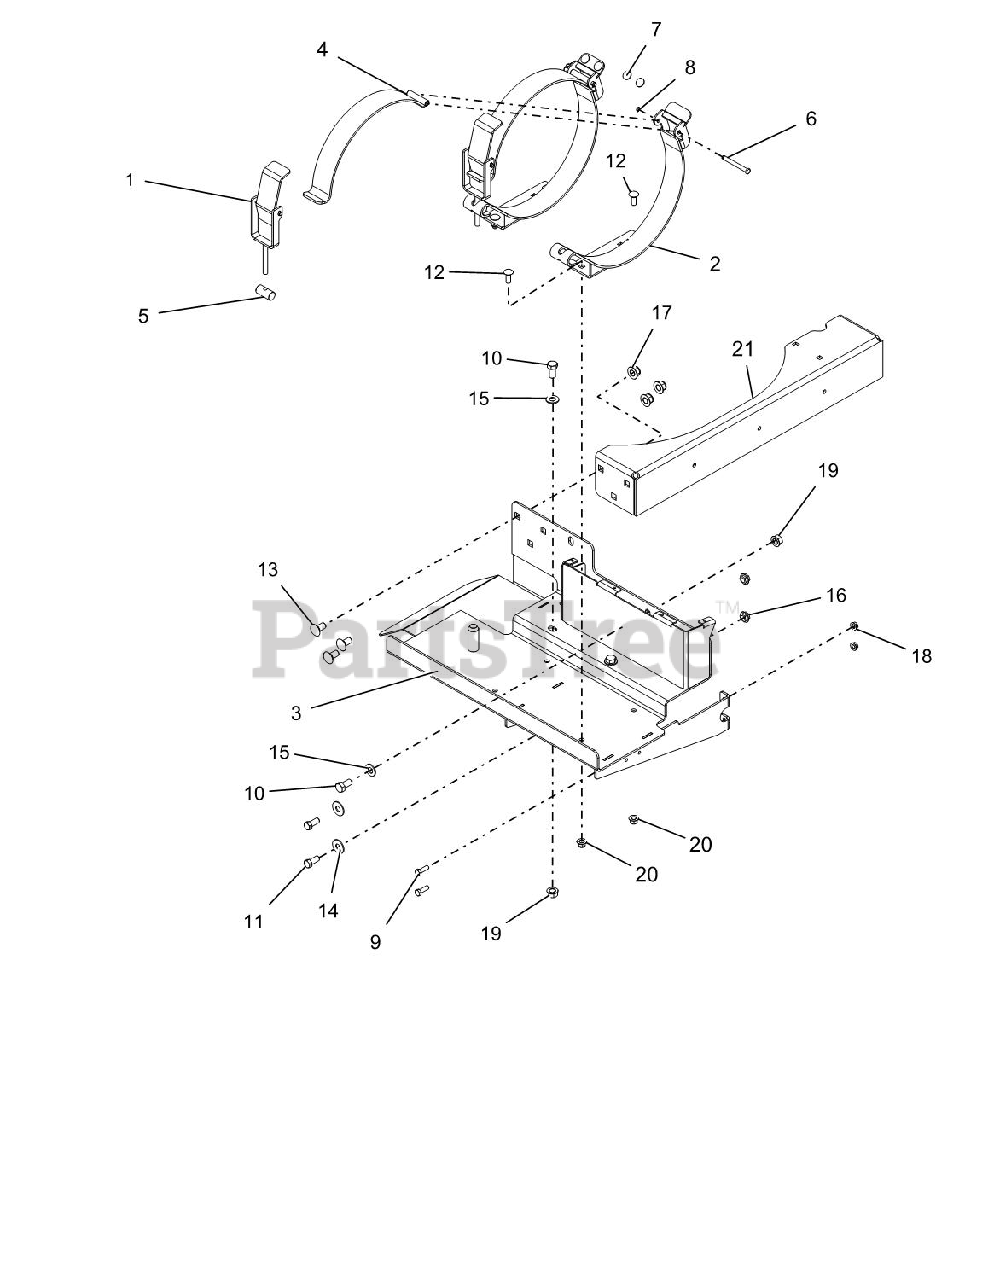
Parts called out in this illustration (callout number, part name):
1	ASM,TOGGLE CLAMP
2	WLDMT, CLAMP LP TANK
3	RH LP TANK MTG W/SAFETY DECAL
4	LP TANK CLAMP W/SAFETY DECAL
5	PIVOT, LP CLAMP HANDLE
6	PIN, LP CLAMP
7	MAGNET, .75X.06, LP CLAMP
8	RG-RTNG-EXT .312X.025
9	BLT-HEX .31-18X1.00 GR5 YWZC
10	BLT-HEX .50-13X1.00 GR5 YWZC
11	BLT-HEX .44-14X1.00 GR5 YWZC
12	BLT-RDHDSQNK .38-16X1.00 G5YZ
13	BLT-RDHDSQNK .50-13X1.00 G5YZ
14	WSHR-FL-STL.50X1.25X.083 YWZC
15	WSHR-FL-STL.531X1.06X.095YWZC
16	NUT-LK-NYL-FLG .44-14 YWZC
17	NUT-LK-NYL-FLG .50-13 YWZC
18	NUT-LK-TOP-FLG .31-18 YWZC
19	NUT-LK-TOP-FLG .50-13 YWZC
20	NUT-LK-NYL-FLG .38-16 YWZC
21	TANK MNT CROSS SUPPORT W/DECAL
